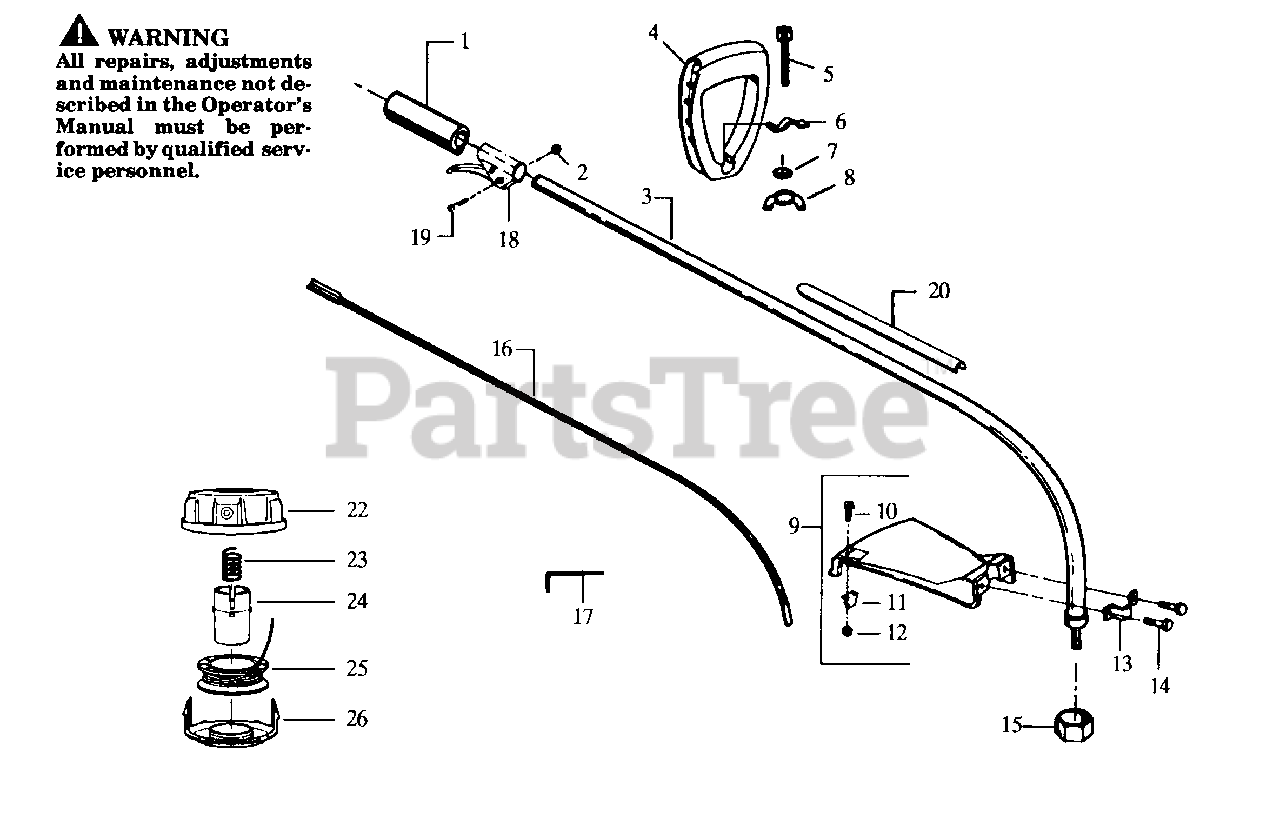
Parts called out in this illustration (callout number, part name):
1	Grip
3	Drive Shaft Housing
4	Handle Ass'y.
9	Shield Kit Ass'y. (Inc.10,11,12,14)
11	Line Limiter
12	Locknut
13	Shield Bracket
14	Screw
15	Dust Cup
16	Drive Shaft
17	Hex Wrench (5/32)
18	Throttle Housing Ass'y.
20	Shaft Warning Decal
22	Hub Ass'y.
24	Release Button
25	Spool w/Line
